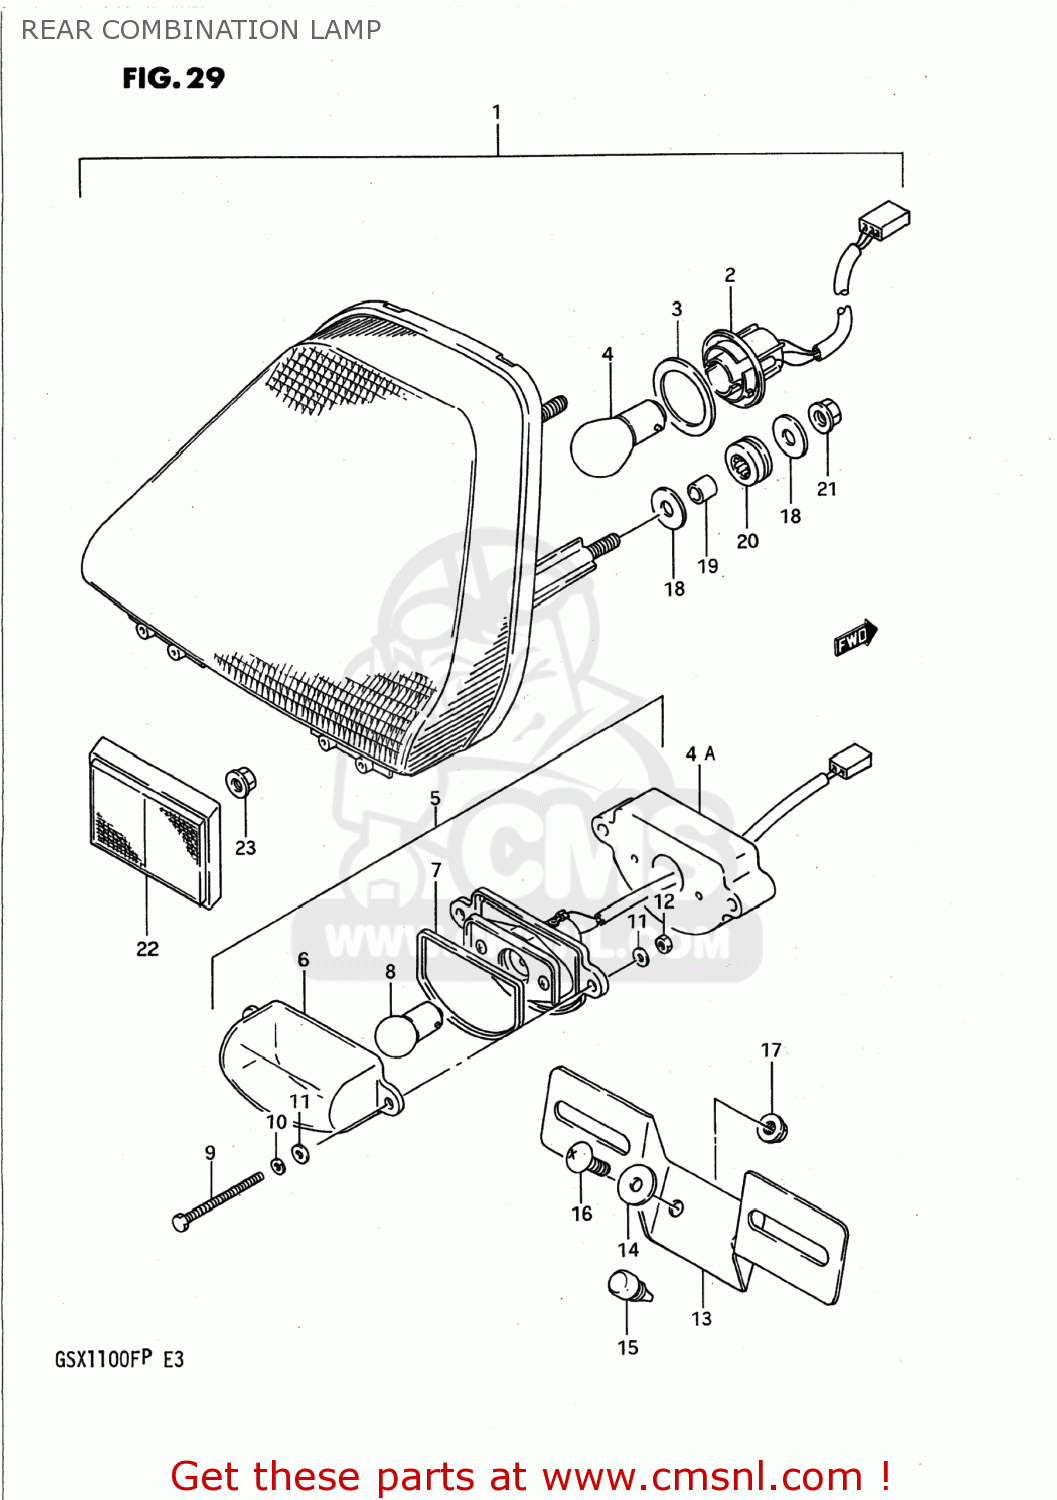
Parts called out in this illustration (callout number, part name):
1	LAMP ASSY,RR COMBINATION
2	SOCKET
3	CUSHION,RUBBER
4	BULB(12V21/5W,BF141-49642A)
4A	SPACER,LICENSE LAMP
5	LAMP ASSY,LICENSE
6	LENS,LICENSE LAMP
7	GASKET,LICESE LAMP (NAS)
8	BULB
9	BOLT
10	WASHER,LOCK 4M
11	WASHER 4MM
12	NUT 4MM
13	BRACKET,LICENSE PLATE
14	WASHER(6.5X20X1.6)
15	CUSHION
16	SCREW
17	NUT 6MM
18	WASHER (6.5X20X1)
19	SPACER (6.1X9X9)
20	CUSHION
21	NUT
22	REAR ASSEMBLY,REAR
23	NUT
